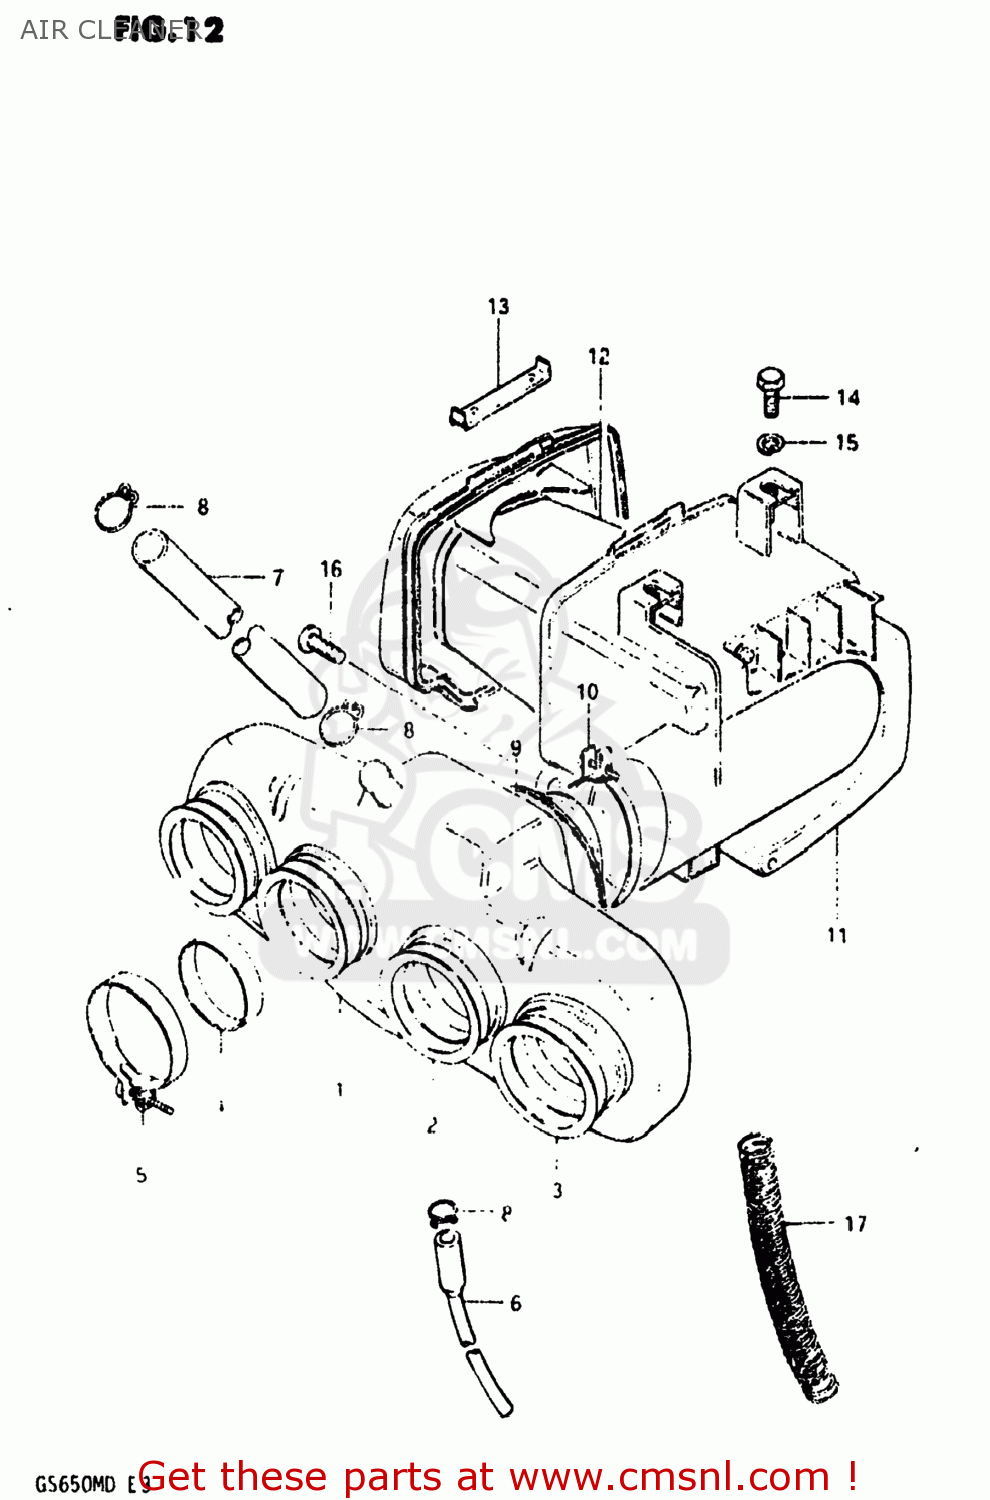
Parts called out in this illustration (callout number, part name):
1	CASE,AIR CLEANER,FRONT
2	TUBE,OUTLET,INNER
3	TUBE,OUTLET OUTER
4	RING,CARBURETOR AIR INLET HOSE
5	CLAMP
6	DRAIN TUBE
7	HOSE
8	CLIP
9	JOINT,HOSE AIR CLEANER
10	CLAMP
11	CLEANER SET,AIR,REAR
12	FILTER ASSY
13	SLIDER
14	BOLT, UPPER
15	LOCK WASHER
16	SCREW
17	SPRING
